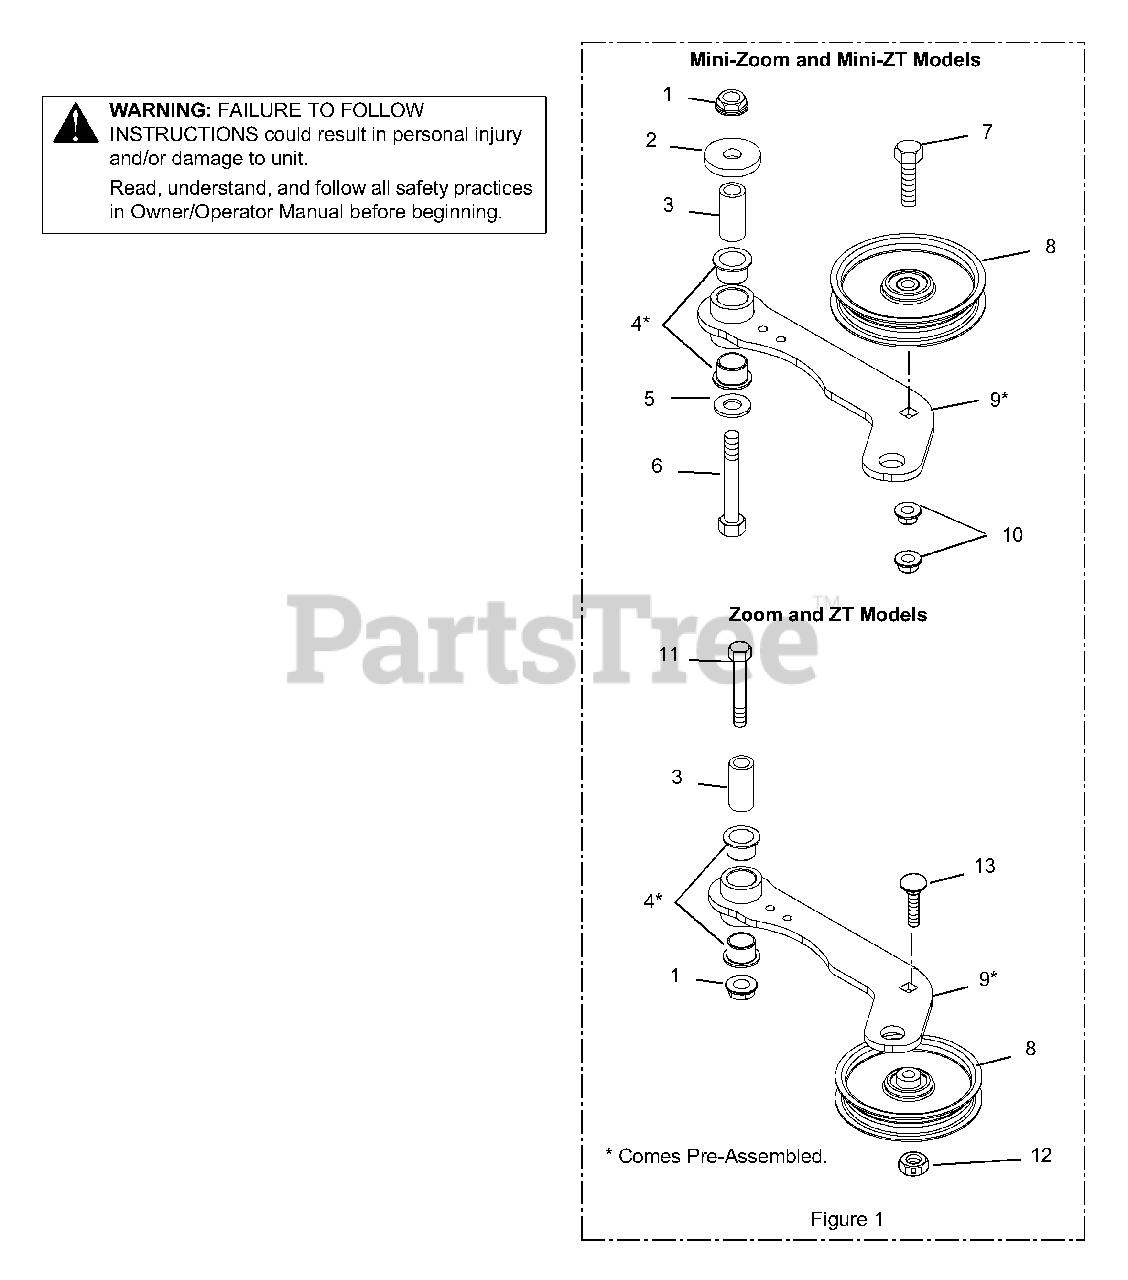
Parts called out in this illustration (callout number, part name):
1	@NUT-LK-TOP-FLG .50-13 YWZC
2	WSHR-FL-STL .515X1.625X.250 YZ
3	BSHG-SLV .500X.750X1.560
4	BSHG-FLG 0.75X0.875X.625X1.125
5	@WSHR-FL-STL.531X1.06X.095YWZC
6	@BLT-HEX .50-13X3.00 GR5 YWZC
7	@BLT-HEX .38-16X2.00 GR5 YWZC
8	IDLER-FLAT 4.00 X .38 NWHAMSHR
9	WMT, IDLER ARM
10	@NUT-LK-NYL-FLG .38-16 YWZC
11	@BLT-HEX .50-13X2.50 GR5 YWZC
12	@NUT-LK-CTR-JAM .375-16 YWZC
13	@BLT-RDHDSQNK .38-16X1.25 G5YZ
